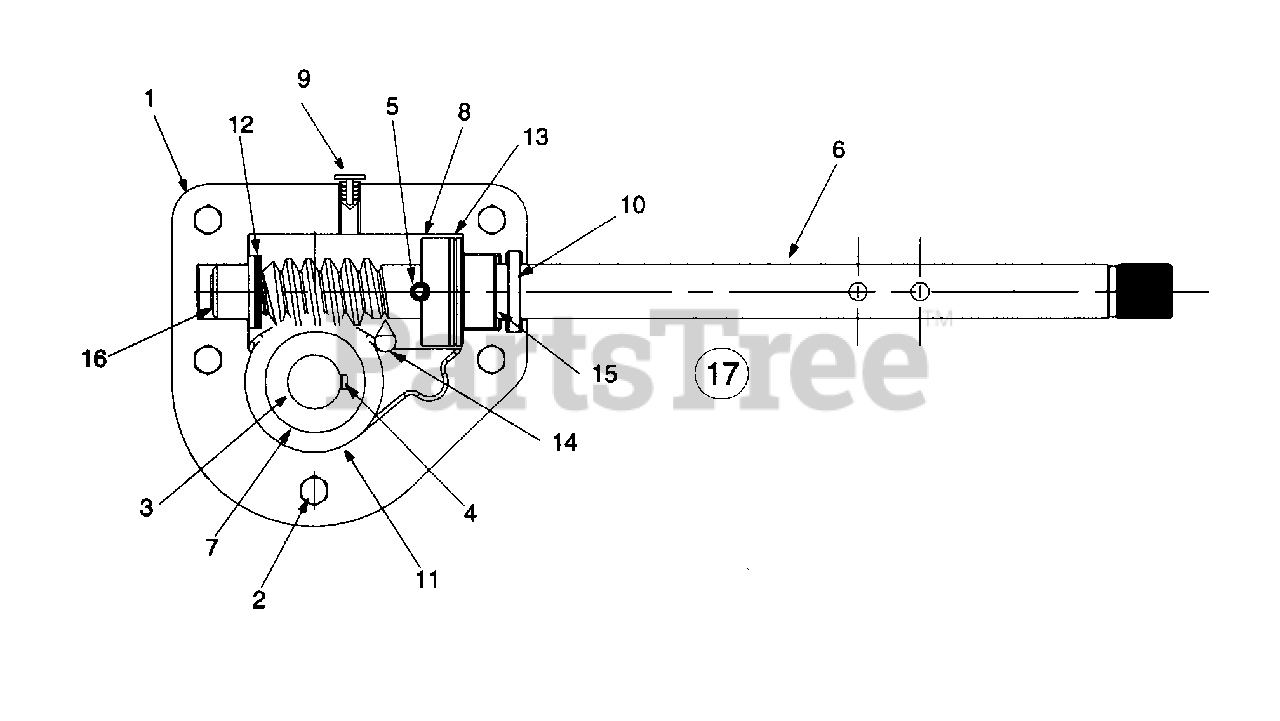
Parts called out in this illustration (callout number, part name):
1	Housing - L.H.
2	Hex Screw 1/4-20 x .75
3	Spiral Axle 26"
4	Key
5	Pin-Spiral
6	Shaft-Worm
7	Gear-Worm
8	Collar-Thrust
10	Seal-Oil
11	Washer-Flat
12	Washer-Flat
13	Washer-Flat
14	Grease
15	Bearing-Flange
16	Bearing-Flange
17	Ass'y. Complete 26"
